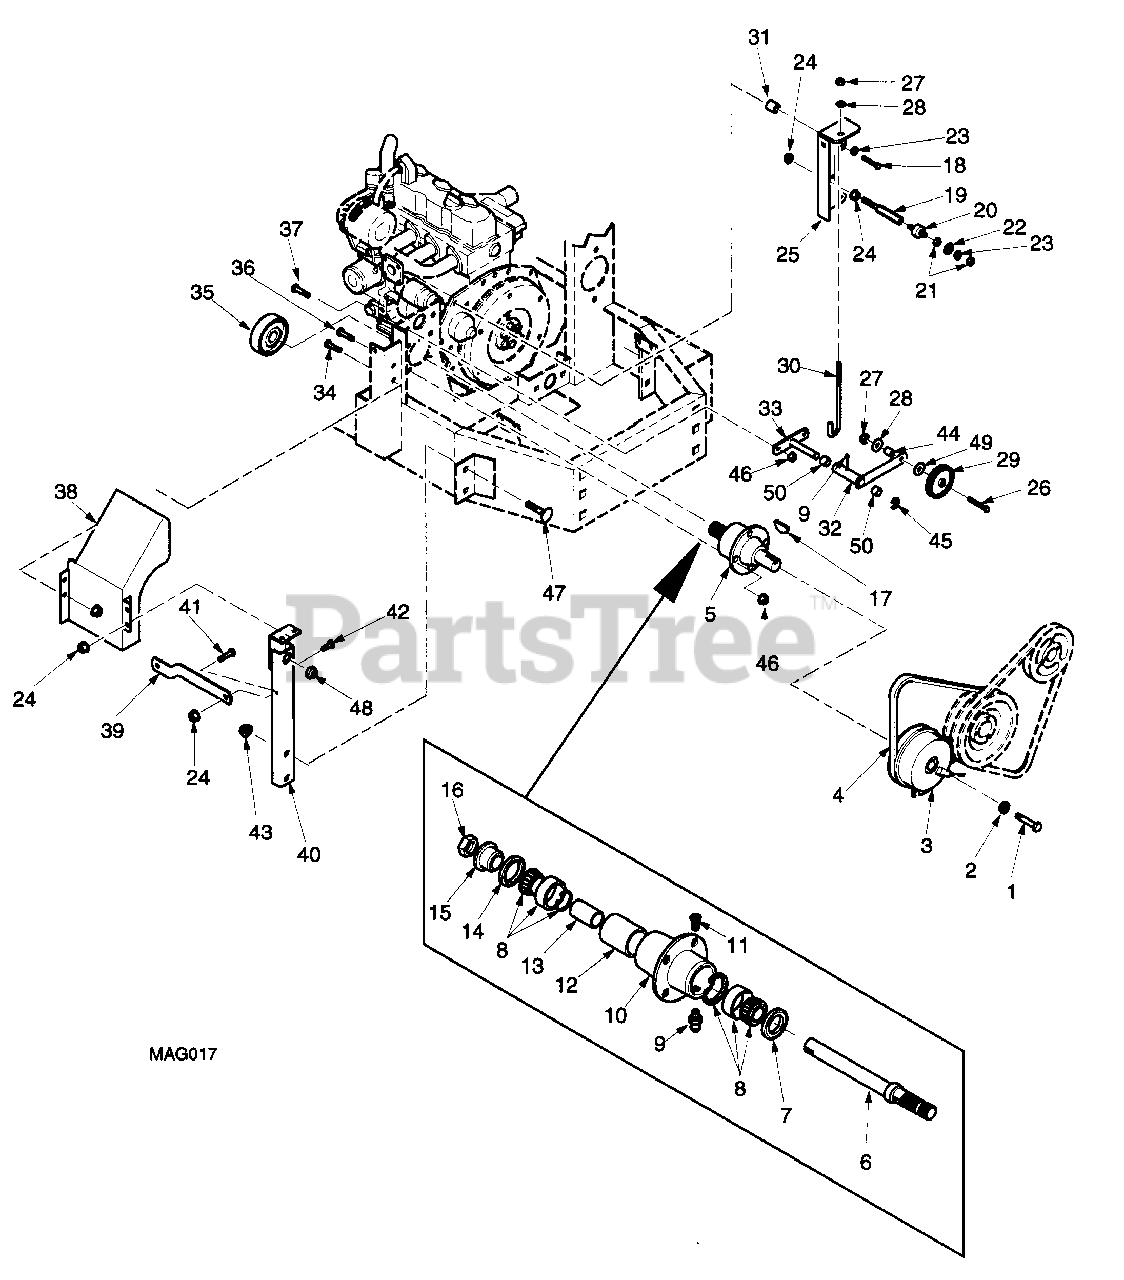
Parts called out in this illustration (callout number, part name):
1	BOLT, HEX HEAD, 7/16-20 X 2-1/2
2	LOCKWASHER, 7/16
3	CLUTCH, ELECTRIC
4	BELT, DECK DRIVE
5	SPINDLE, DECK DRIVE(INCLUDES 6 THRU 16)
6	SHAFT, DECK DRIVE
7	SEAL, 2.00 O.D. 1-1/2 BORE
8	ROLLER BEARING(REPLACE AS A SET ONLY)
9	GREASE FITTING
10	HOUSING, SPINDLE
11	RELIEF FITTING
12	SPACER, OUTSIDE
13	SPACER, INSIDE
14	SEAL, 2.00 O.D. X 1-5/8 BORE
15	SPINDLE BUSHING, BOTTOM
16	NUT, 1-1/16-18
17	KEY, #807 WOODRUFF, 1/4 X 7/8
18	BOLT, HEX HEAD, M8-1.25 X 40
19	PIN, CLUTCH ANTI-ROTATION
20	ISOLATOR, RUBBER
21	NUT, HEX, 5/16-18
22	FLATWASHER, 5/16(.375 X .875 X .083)
23	LOCKWASHER, 5/16
24	SERR. FL. HEX NUT, 3/8-16
25	ANCHOR BRACKET, J-BOLT
26	BOLT, HEX HEAD, 3/8-16 X 2-1/4
27	HEX LOCKNUT, ELASTIC STOP, 3/8-16
28	FLATWASHER, 3/8(.391 X .938 X .105)
29	PULLEY, IDLER
30	ROD, J-HOOK
31	SPACER
32	IDLER ARM, CLUTCH
33	BRACKET, IDLER PIVOT
34	SERR. FL. HEX HEAD CAPSCREW, 5/16-18 X 3/4
35	HUB, BRAKE
36	BOLT, HEX HEAD, 5/16-18 X 1-1/4
37	SERR. FL. HEX HEAD CAPSCREW, 5/16-18 X 1-1/2
38	BELT GUARD, ELECTRIC CLUTCH
39	BRACE, FAN SUPPORT - LH
40	UPRIGHT, FAN SUPPORT - LH
41	SERR. FL. HEX HEAD CAPSCREW, 3/8-16 X 1
42	CARRIAGE BOLT, 5/16-18 X 3/4
43	SERR. FL. HEX NUT, 1/2-13
44	SPACER, J PULL ROD
45	RETAINING RING, .75 EXT
46	SERR. FL. HEX NUT, 5/16-18
47	CARRIAGE BOLT, 1/2-13 X 1-1/4
48	LOCK NUT, ELASTIC STOP, 1/2-13
49	FLAT WASHER, 3/8(.406 X 1.50 X .179)
50	BUSHING, OILITE - .753 I.D.
